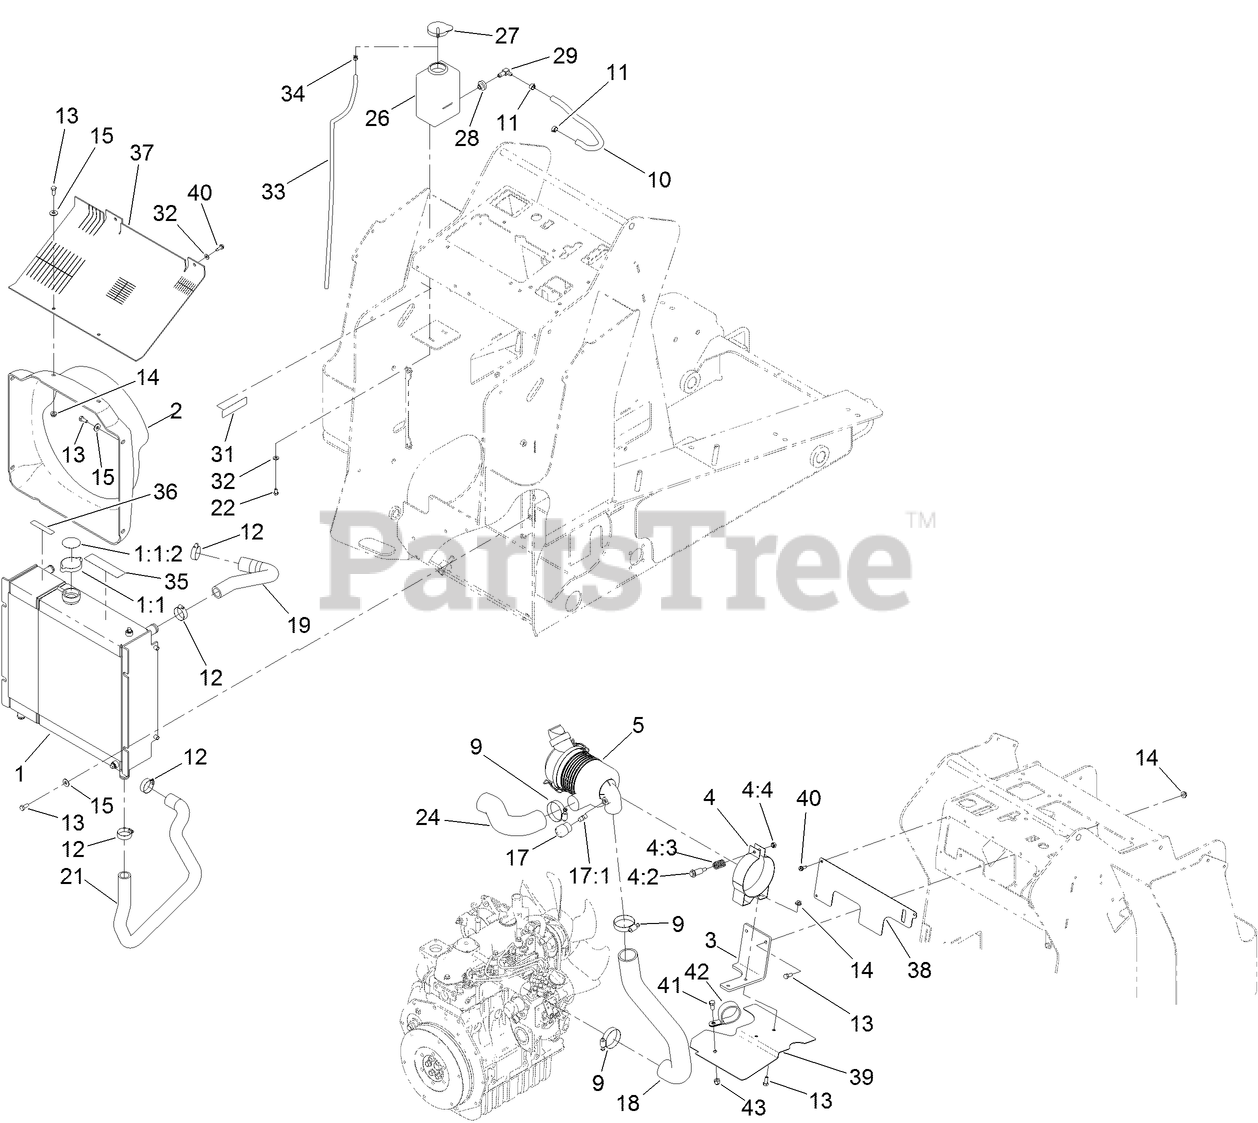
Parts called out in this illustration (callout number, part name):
1	COOLING ASM
1:1	RADIATOR CAP ASM
1:1:2	DECAL-DANGER
2	SHROUD-FAN
4	AIR CLEANER MOUNTING BAND ASM
4:3	SPRING
4:4	NUT
5	AIR CLEANER ASM
9	CLAMP-HOSE
10	HOSE-FUEL
11	CLAMP-HOSE
12	CLAMP-HOSE
13	SCREW-HH
14	NUT-HF
15	WASHER-FLAT
17	INDICATOR
17:1	ADAPTER-INDICATOR
18	HOSE-INTAKE, ENGINE
19	HOSE-RADIATOR
21	HOSE-RADIATOR, LOWER
22	SCREW-HH
24	HOSE-AIR, INLET
26	TANK-OVERFLOW
27	CAP-TANK, OVERFLOW
28	BUSHING
29	FITTING-ELBOW-90
31	DECAL-RADIATOR FILL
32	WASHER-FLAT
33	HOSE-LP
34	CLAMP-HOSE
35	DECAL-DANGER
36	DECAL-WARNING, FAN
37	GUARD-AIR
38	COVER-AIR
39	BAFFLE-HEAT
40	SCREW-HWH, THREAD ROLL
41	SCREW-HH
42	CLAMP-R
43	NUT-LOCK, NI
